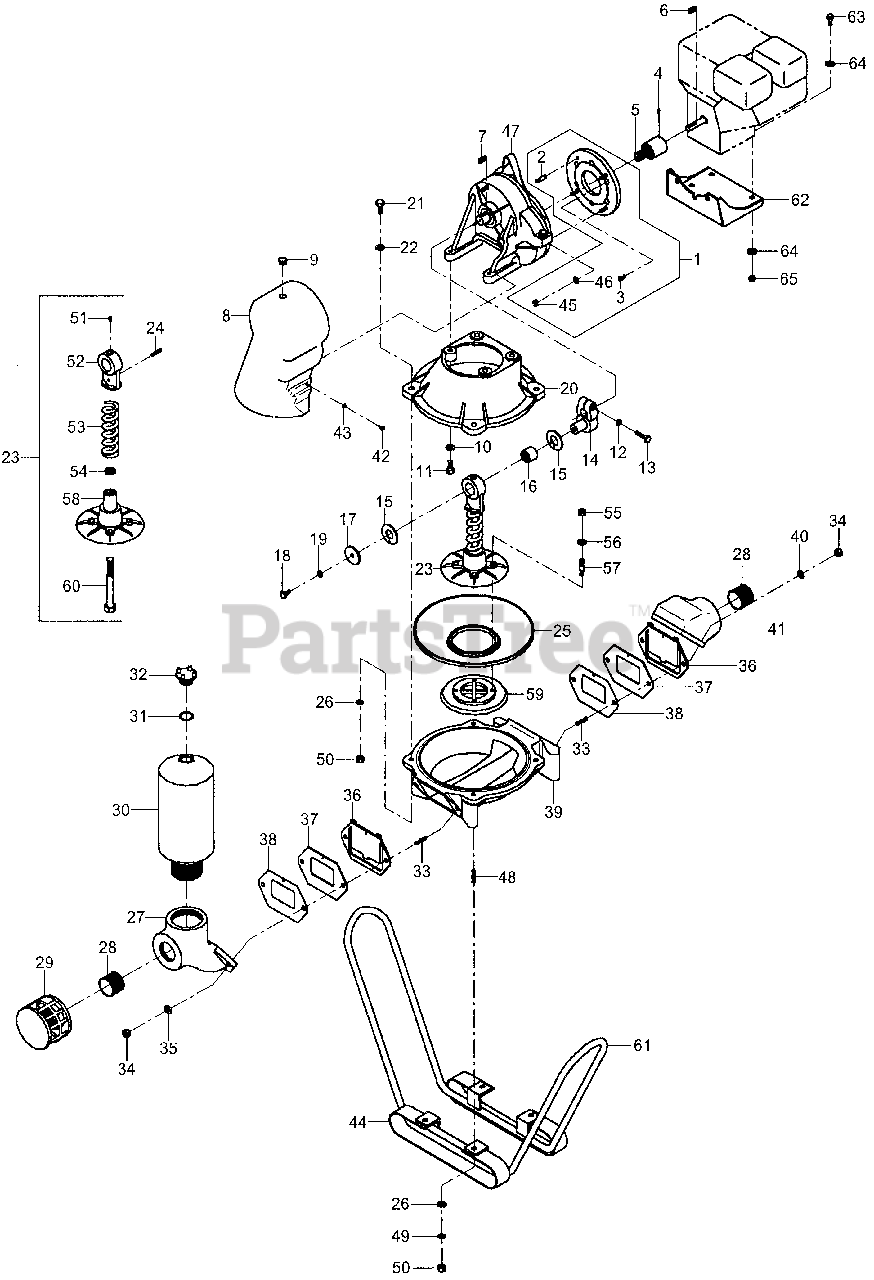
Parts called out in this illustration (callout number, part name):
1	ADAPTER, ENGINE
2	STUD (10X1.5X40) (W/NUT)
3	SCREW, ALLEN
3	SCREW, ALLEN (8X1.25X15)
4	SCREW SET (8MX1.25X10)
6	KEY STOCK (3/16X1)
8	COVER *R1* (RED)
9	PLUG, COVER (#35)
10	WASHER, PLAIN (12MM)
11	BOLT, HEX.
11	BOLT, HEX. (12X1.75X40)
12	WASHER, SPRING (10MM)
13	BOLT, HEX.
13	BOLT, HEX. (10X1.5X40)
14	CRANK (2" PUMP)
15	WASHER, FIBER
16	BEARING, CRANK
17	COVER, CONNECTING ROD BUSHING
18	BOLT, HEX.
19	WASHER, SPRING (10MM)
20	CASE, MOUNTING (UPPER) (ALUMINUM)
21	BOLT, HEX. (12X1.75X50)
22	WASHER, PLAIN (12MM)
23	ROD, CONNECTING
24	NIPPLE, GREASE
25	DIAPHRAGM, NEOPRENE
26	WASHER, FLAT (12MM)
26	WASHER, PLAIN (12MM)
27	PORT, SUCTION BPST (2")
27	PORT, SUCTION NPT (2")
28	NIPPLE (2")
29	STRAINER, TRASH (2" SQUARE HOLE)
30	CHAMBER, AIR BPST
30	CHAMBER, AIR NPT (3")
31	O-RING, AIR CHAMBER PLUG
32	PLUG, AIR CHAMBER (BRONZE)
33	STUD, FLANGE
34	NUT (12X1.75)
35	WASHER, FLAT (12MM)
35	WASHER, PLAIN (12MM)
36	CLAPPET, NEOPRENE
37	WEARPLATE, STAINLESS STEEL
38	GASKET, WEARPLATE PAPER
39	CASE (LOWER) (ALUMINUM)
40	WASHER, FLAT (12MM)
40	WASHER, PLAIN (12MM)
41	PORT, DISCHARGE (2")
42	BOLT, HEX. (8x1.25x15)
43	WASHER, FLAT (8MM)
43	WASHER, PLAIN (8MM)
44	SPRING, FRAME
45	NUT (10x1.5)
46	WASHER, SPRING (10MM)
47	TRANSMISSION, STRAIGHT TEETH (1:43)
48	STUD, PUMP CASE MOUNTING
49	WASHER, STAR (12MM)
50	NUT (12X1.75)
51	ROD END (UPPER)
53	SPRING, CONNECTING ROD
54	RING (INNER)
55	NUT (12X1.75)
56	WASHER, FLAT (12MM)
56	WASHER, PLAIN (12MM)
57	STUD (12X1.75-70)
58	ROD END (LOWER)
59	FLANGE, CONNECTING ROD
60	BOLT, SPECIAL
61	FRAME ASSY., SKID
62	BRACKET, ENGINE MOUNTING
63	BOLT, HEX. (5/16-18X1.5")
64	WASHER, FLAT (5/16" SAE)
65	LOCKNUT (5/16X18") (NYLOCK)
